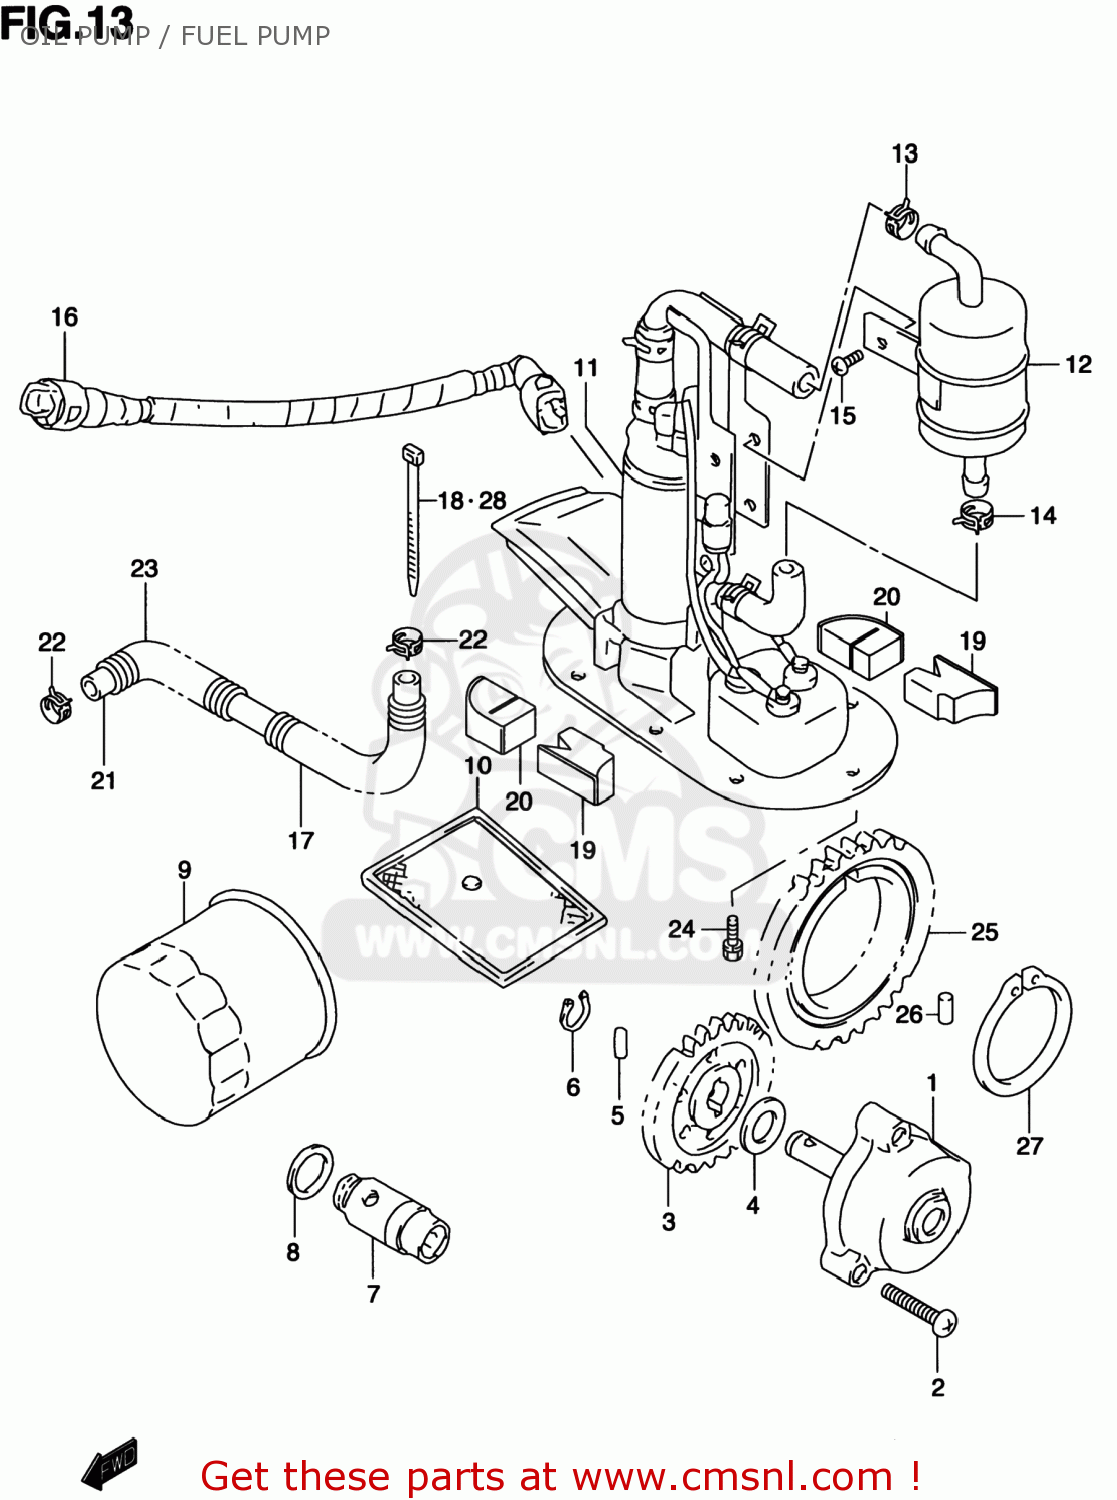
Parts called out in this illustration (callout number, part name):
1	PUMP ASSEMBLY,ENGINE OIL
2	SCREW
3	GEAR,OIL PUMP DRIVEN
4	SHIM(10X18X0.5)
5	PIN(4X15.8)
6	CIRCLIP,10MM
7	VALVE ASSY,OIL RELIEF
8	GASKET(16X22X2) (NAS)
9	FILTER ASSEMBLY,ENGINE OIL
10	STRAINER,ENGINE OIL
11	PUMP ASSY,FUEL
12	FILTER,FUEL
13	CLIP
14	CLIP
15	SCREW
16	HOSE,FUEL
17	PROTECTOR,FUEL RETURN NO,2
18	CLAMP(L:80)
19	SPACER
20	SPACER,FUEL PUMP NO.2
21	HOSE(5.4X11.4X600)
22	CLIP
23	(CA) SPRING
24	BOLT,FUEL PUMP
25	GEAR,ENG OIL PUMP DRIVE
26	PIN(6X6)
27	CIRCLIP
28	CLAMP(L:125)
